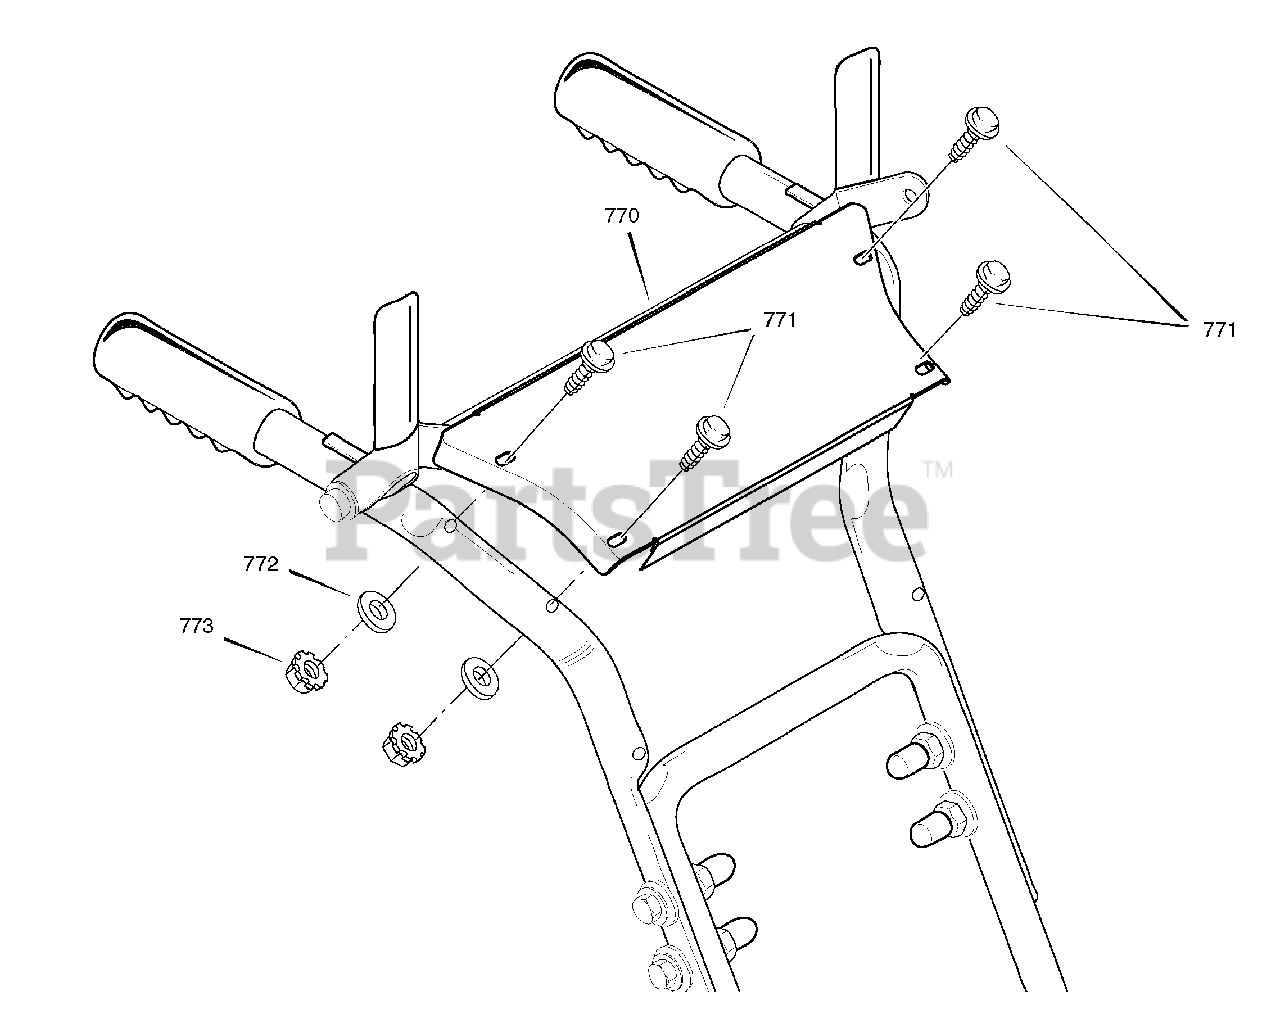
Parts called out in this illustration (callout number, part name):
771	BOLT, Carriage, 25-20 X 1-1/2"
772	WASHER
773	NUT
